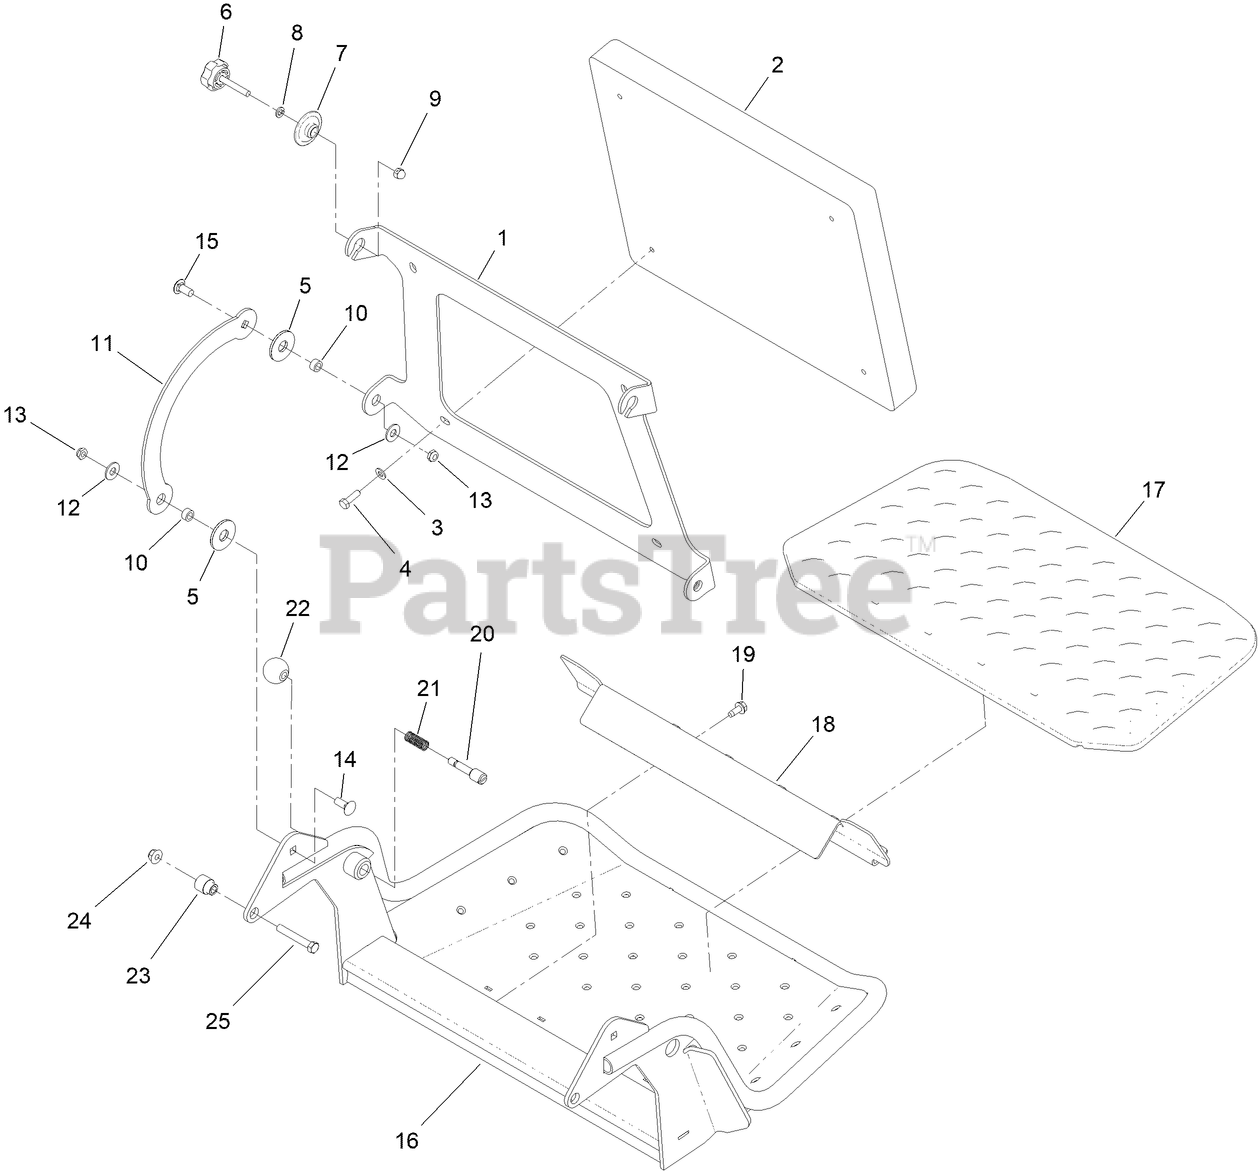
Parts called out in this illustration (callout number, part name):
1	HINGE-PAD
2	CUSHION-PAD
3	WASHER-PLAIN
4	SCREW-HH
5	WASHER-FRICTION, COMPOSITE
7	SLIDE-BUSHING
8	WASHER-LOCK
9	NUT-ACORN
10	SPACER
11	LINK-PAD
12	WASHER-FLAT
14	BOLT-CARR
15	SCREW-CARR
16	PLATFORM ASM [RED]
17	MAT-PLATFORM
18	SHIELD CLAMP KIT
19	SCREW-HWHTF
20	PIN-LATCH
21	SPRING
22	KNOB-BALL
23	BUSHING-FLANGED
24	NUT-HF, NI
25	SCREW-HH
